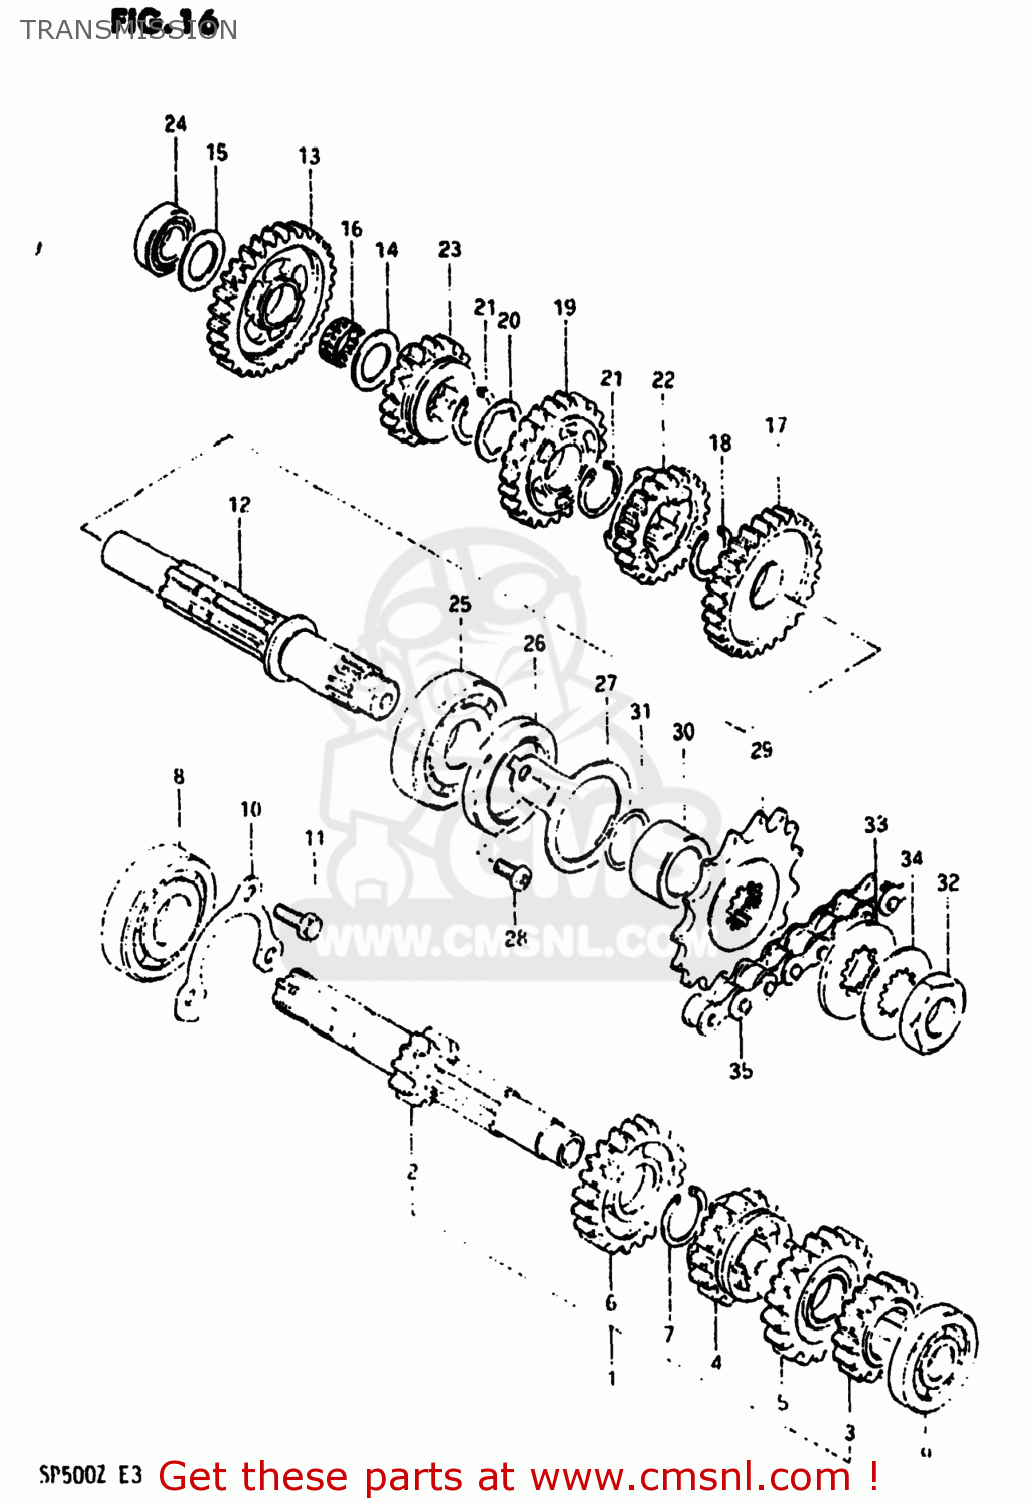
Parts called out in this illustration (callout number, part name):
1	SHAFT,COUNTER
2	SHAFT,COUNTER
3	GEAR,SECOND DRIVE
4	GEAR,THIRD DRIVE
5	GEAR,FOURTH DRIVE
6	GEAR,FIFTH DRIVE
7	CIRCLIP
8	BEARING
9	BEARING
10	PLATE,COUNTERSHAFT BEARING
11	BOLT
12	SHAFT,DRIVE
13	GEAR,FIRST DRIVEN
14	WASHER
15	WASHER
16	BEARING(20X24X10).8
17	GEAR,SECOND DRIVEN
18	CIRCLIP
19	GEAR,THIRD DRIVEN
20	WASHER,LOCK
21	CIRCLIP
22	GEAR,FOURTH DRIVEN
23	GEAR,FIFTH DRIVEN
24	BEARING(20X42X12)
25	BEARING
26	SEAL,OIL(32X42X7)
27	PLATE,DRIVESHAFT OIL
28	BOLT
29	SPROCKET,ENGINE(NT:15)
30	SPACER (22X32X13.4)
31	O RING(D:1.7,ID:22)
32	NUT
33	SPACER,ENGINE SPROCKET
34	WASHER,LOCK
35	CHAIN ASSEMBLY,DRIVE
